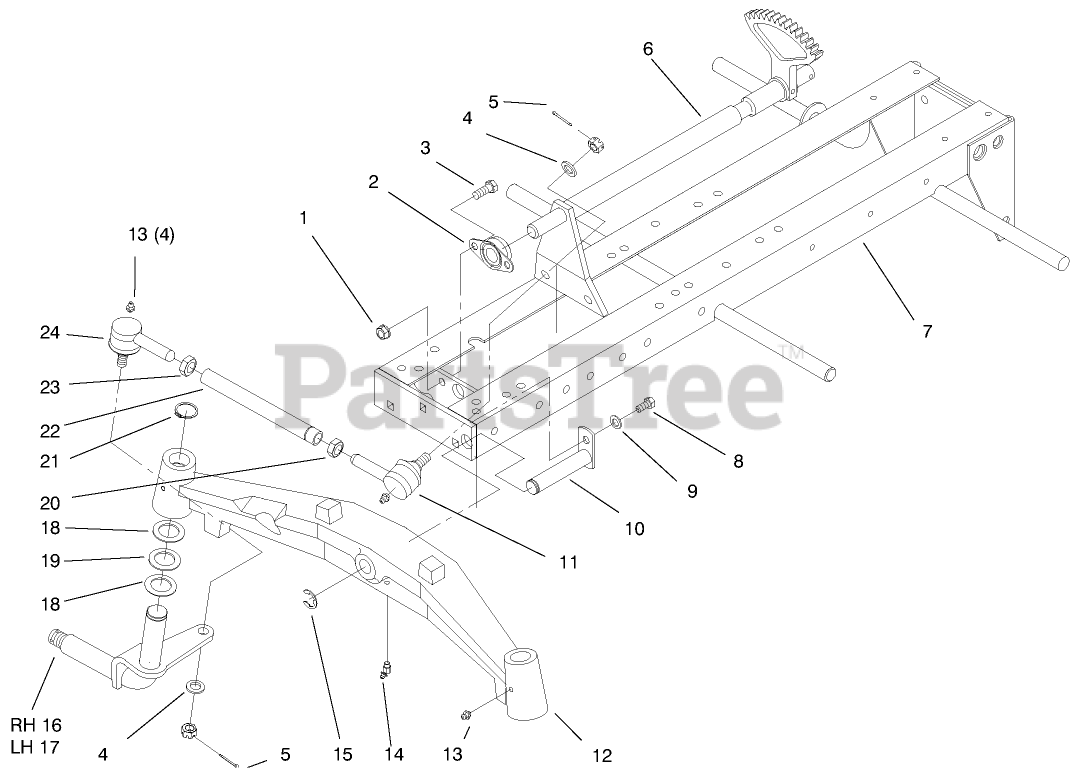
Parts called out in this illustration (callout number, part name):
1	NUT-LOCK, NI
2	BEARING-FLANGED
3	SCREW-HH
5	PIN-COTTER
7	WA FRAME
8	SCREW-HH
9	WASHER-LOCK
10	PIN AND PLATE ASM
11	Balljoint-RH Thread
13	FITTING-GREASE
14	FITTING-LUBE, 45 DEG
15	E-RING
17	L.H. SPINDLE WA
18	WASHER-THRUST
20	NUT-JAM
21	RING-RETAINING
23	NUT-HEX JAM 9/16-18
24	Balljoint-LH Thread
